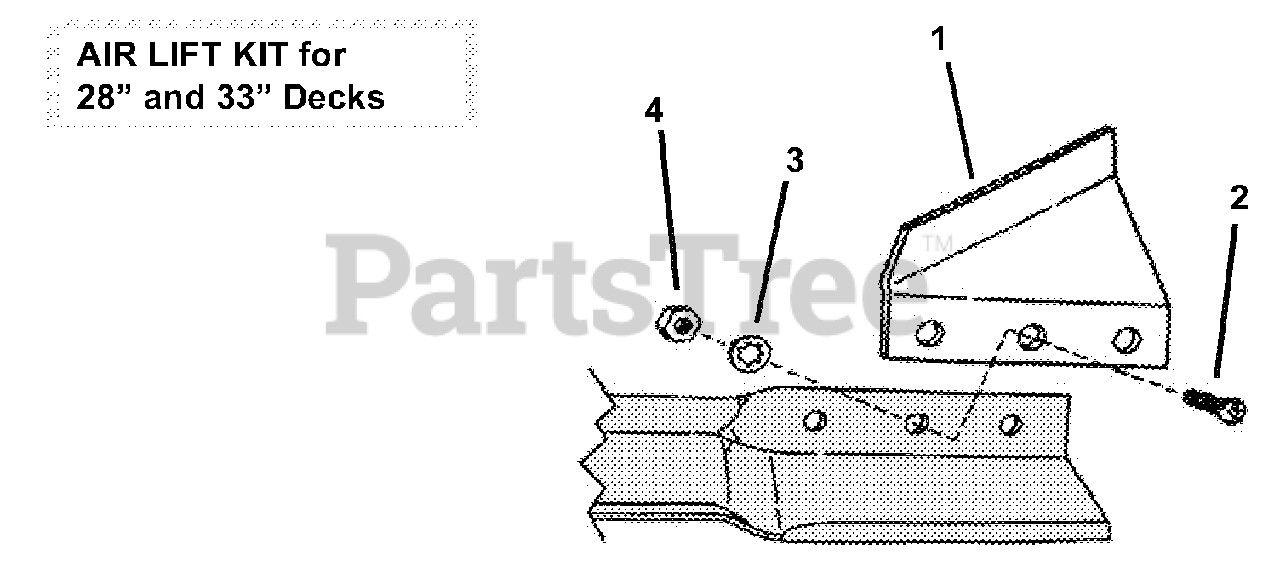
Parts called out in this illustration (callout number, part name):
1	AIR LIFT, 28" & 33"
2	SCREW, 5/16-24 Machine
3	WASHER, 5/16" Internal Tooth Lock
4	NUT, 5/16-24 Hex
